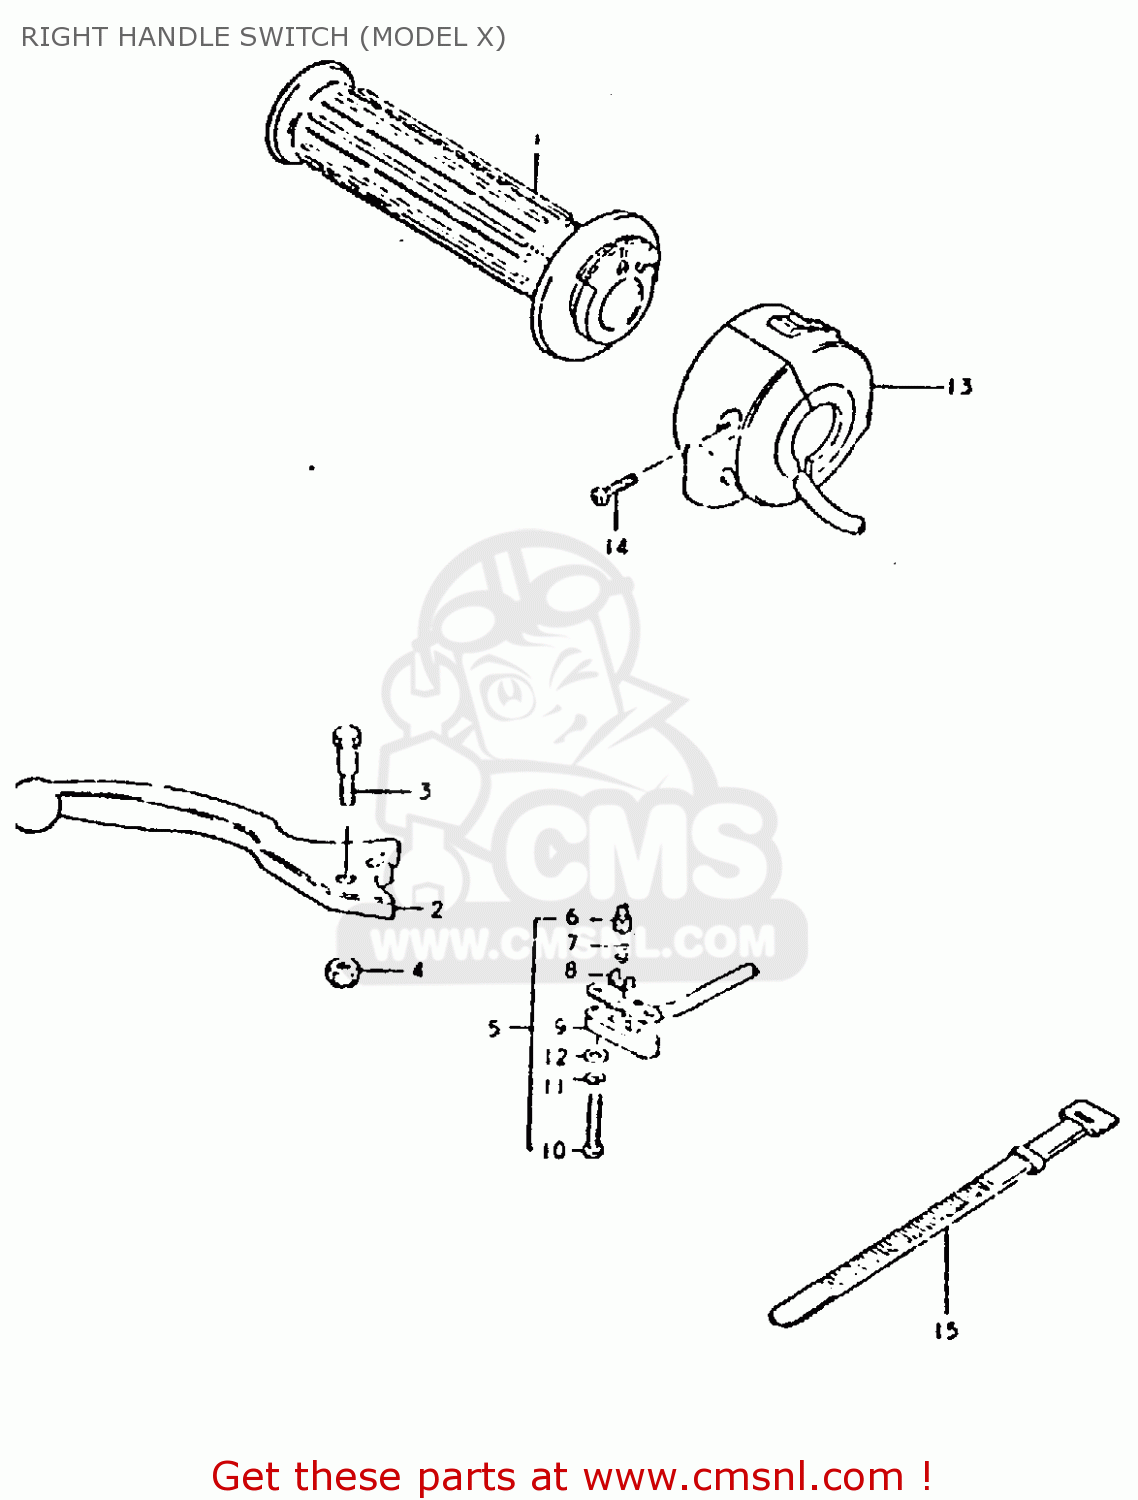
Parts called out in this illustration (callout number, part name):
1	GRIP,THROTTLE
2	LEVER,BRAKE
3	BOLT
4	NUT 6MM
5	SWITCH ASSEMBLY
6	HOLDER
7	SPRING
11	LOCK WASHER
12	WASHER
13	SWITCH ASSY, HANDLE RH
14	SCREW
15	CLAMP(L:120)
